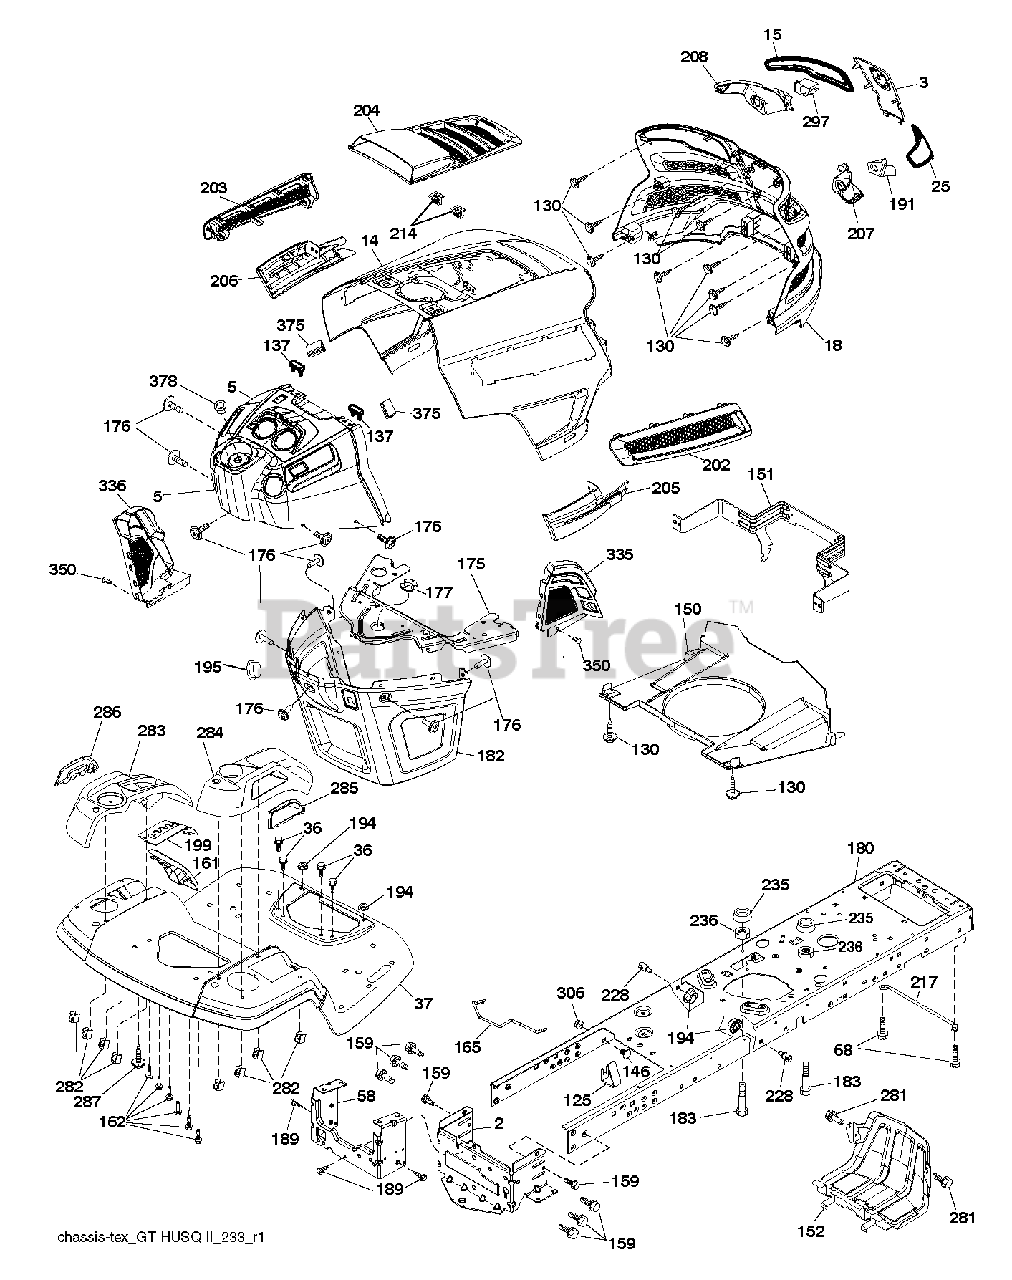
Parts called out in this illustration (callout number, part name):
2	DRAWBAR.LOWER.2PC.18/22
3	APPLIQUE.SUBASM.GT.HUSQ.II
5	DASHBOARD.TEX.GT2.UPPER.S.PTO
14	HOOD.ASM.HUSQVARNA.GT.TEX.ORAN
15	LENS.HEADLIGHT.LH.GTII.2011
18	GRILLE SUBASM.GT.II.LOW.HDLGHT
25	LENS.HEADLIGHT.RH.GTII.2011
36	SCREW 5/16"
37	FENDER.TLT.FS.W/CPH/FW/RSF.668
58	DRAWBAR UPPER 2PC SMALL FENDER
68	SCR 5/16-18 X 1/2 SELFTAP ZN
125	CLIP.FUEL.LINE
130	SCREW.#10 X 0.750.BOS
137	BUMPER DASH
146	BOLT.RDHD.SHT.SQNK.3/8-16X5/8
150	AIR.DUCT.GTV.BLACK
151	BRACKET.PIVOT.HOOD.GT.HUSQ.II
152	SHIELD.BROWNING.PNT.GT.V2
159	SCREW, 3/8-16X3/4
161	WINDOW.FUEL.LT.HUSQ.TEX.498
162	SCREW.HI-LO.CONSOLE
165	SUPPORT.TANK.REAR.B/TE
175	Crossmember Plate
176	SCREW.#10-24X5/8.RN.QU
177	BUSHING STEERING
180	CHASSIS.LT/GT.BOLTED
182	DASH.LOWER.COMMON.12V.ADAPTOR
183	BOLT.5/16-18X1-1/4 FULL THD
189	SCREW
191	INSERT.REFLECTIVE.RH.HUSQ.GTII
194	NUT LOCK HEX FLANGE 5/16-18
195	PLUG.HOLE.DASH.LOWER.12V.BLK
199	PLATE.DECK.LIFT.HUSQ.LT
202	VENT.SIDE.RH.GT.HUSQ.II.
203	VENT.SIDE.LH.GT.HUSQ.II.498
204	VENT.TOP.HUSQ.GT2
205	SIDE.TRIM.RH.GT.HUSQ.II
206	SIDE.TRIM.LH.GT.HUSQ.II.GRAY
207	HEADLIGHT.CUP.BEZEL.HUS.GT2.RH
208	HEADLIGHT.CUP.BEZEL.HUS.GT2.LH
214	CLIP.RETAINER.TINNER.
217	ROD.PIVOT.HOOD
228	STUD.FASTNER.W/ANTI-ROTATE
235	SPACER FENDER
236	NUT.CENTERLOCK.5/16-
281	SCREW 3/8-16X1
282	CLIP.RETAINER.CONSOLE.LT.HUSQ
283	CONSOLE.DECK.LIFT.R.SDFL.HUSQ
284	CONCOLE.CNTRL.PDL.HUSQ.LT.498
285	CONSOLE INSERT RH
286	CONSOLE.INSRT.LH.HUSQ.LT.BLACK
287	SCREW 1/4X20
297	INSERT.REFLECTIVE.LH.HUSQ.GTII
306	NUT LOCK FLG 3/8-16 UNC
335	COVER.LOWER.DASH.RH.BLACK
336	COVER-LH.LOWER.DASH.GT2.BLACK
350	CLIP.X-MAS.TREE
375	BUMPER CLIP-ON. DASH 1"
378	BUSHING FLANGE; PLASTIC
